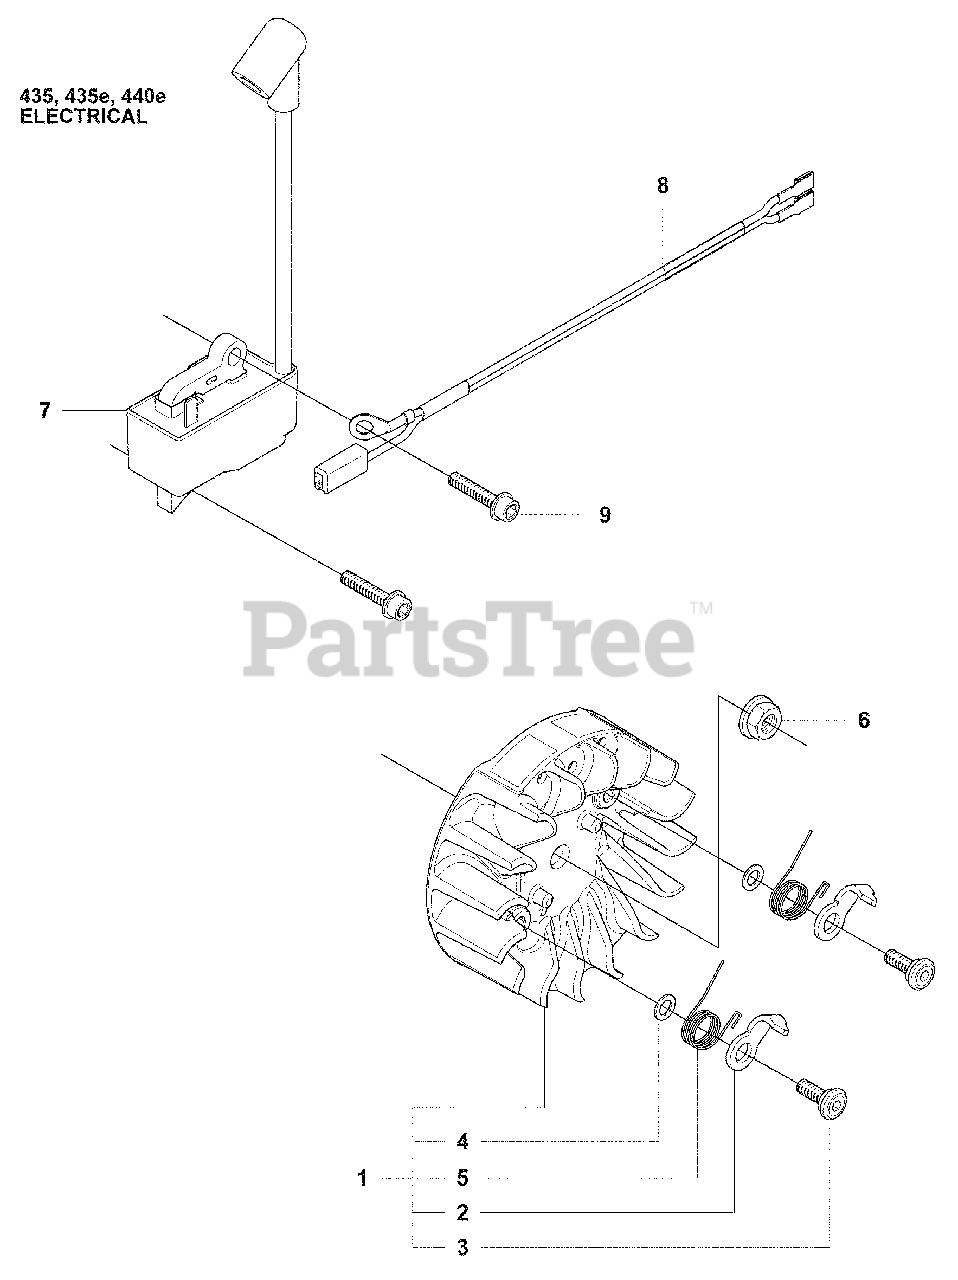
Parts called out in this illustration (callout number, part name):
1	Flywheel Assembly
2	Starter Pawl
3	Starter Catch Screw
4	Washer
5	Spring
6	Nut with Washer
7	Ignition Module, WALBRO MBU
8	Wiring Assembly
9	Screw
